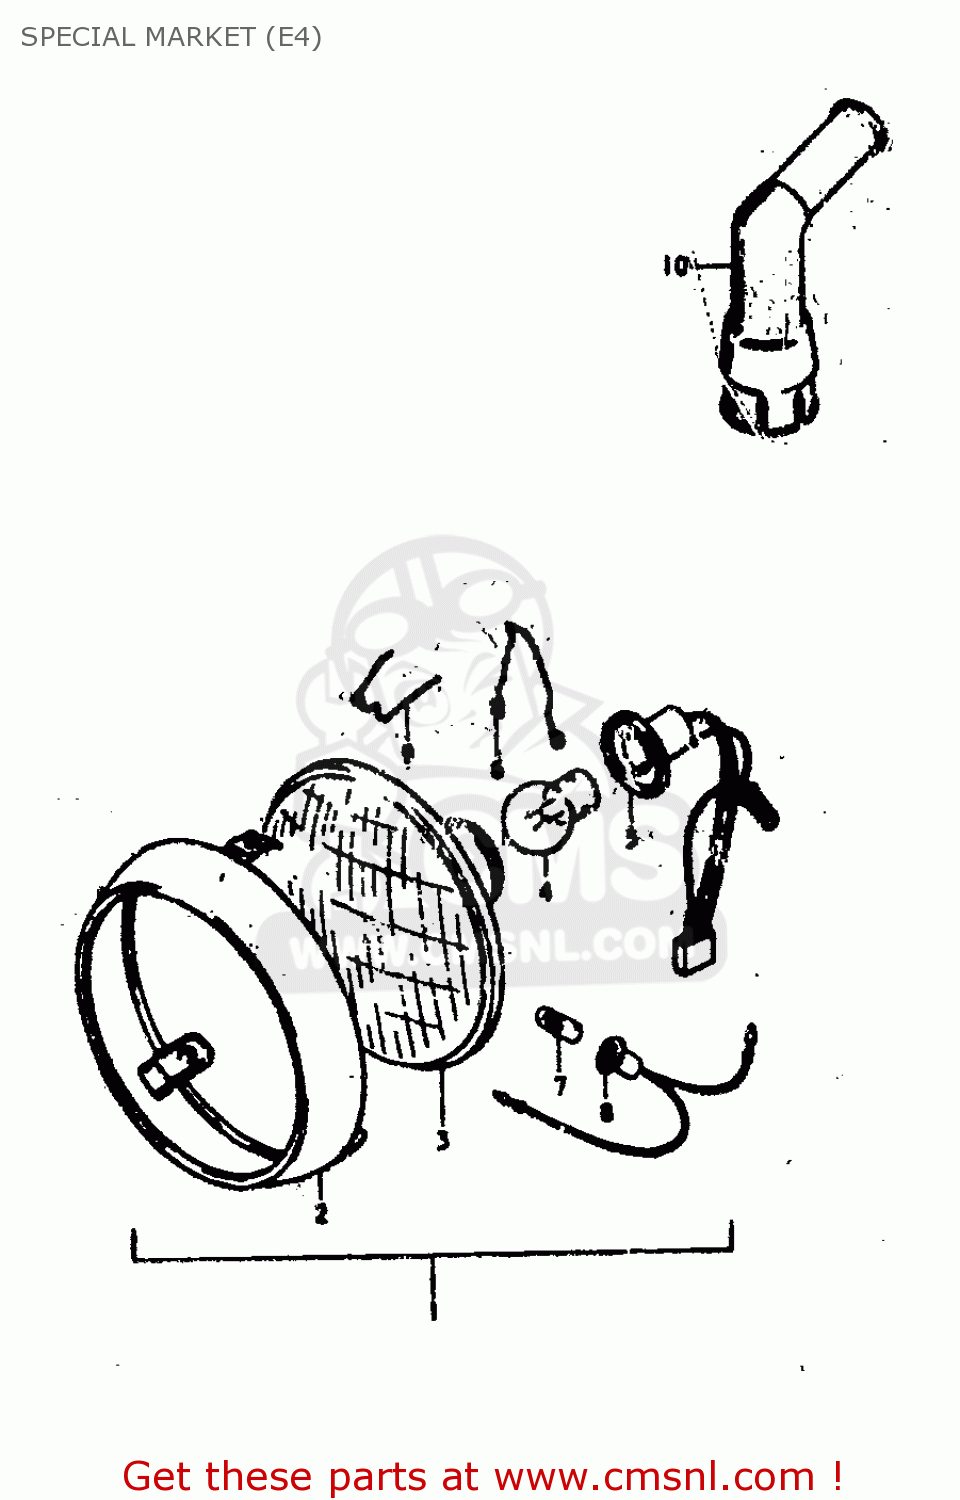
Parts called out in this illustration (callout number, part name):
1	HEADLAMP ASSY
2	RIM
3	UNIT
4	BULB
5	SOCKET
6	CLAMP,HEADLAMP
7	BULB(12V4W)
8	SOCKET
9	SPRING,HEAD LA
10	CAP, SPARK PLUG (S)
